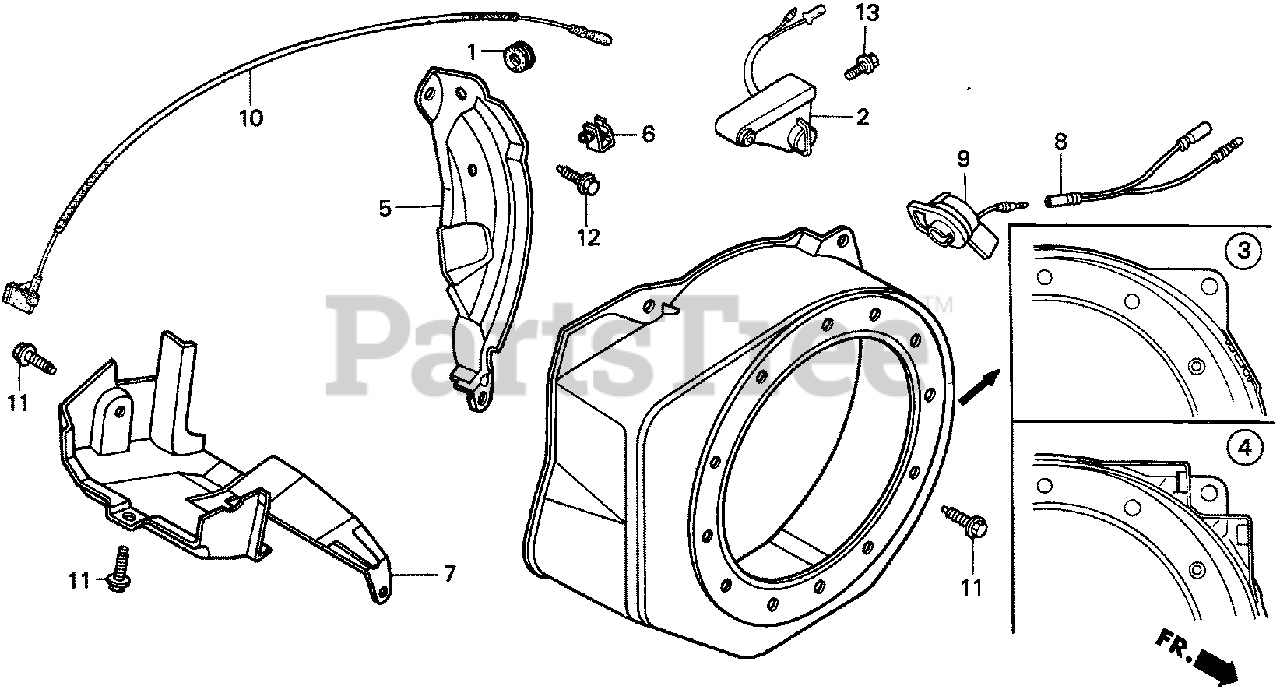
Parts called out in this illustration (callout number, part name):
1	GROMMET, ADJUSTING COVER
2	ALERT UNIT, OIL
3	COVER, FAN *R8* (BRIGHT RED)
3	COVER, FAN *T51* (JACOBSEN ORANGE)
4	COVER, FAN *R8* (OIL ALERT) (BRIGHT RED)
5	PLATE, SIDE (OIL ALERT)
6	CLAMP, WIRE
6	CLAMP, CORD
6	CLIP, HARNESS
7	SHROUD
8	SUB-HARNESS
9	SWITCH ASSY., ENGINE STOP
10	WIRE, STOP SWITCH (370MM)
11	BOLT, FLANGE (6X12) (CT200)
12	BOLT, FLANGE (6X20) (CT200)
13	BOLT, FLANGE (6X8)
